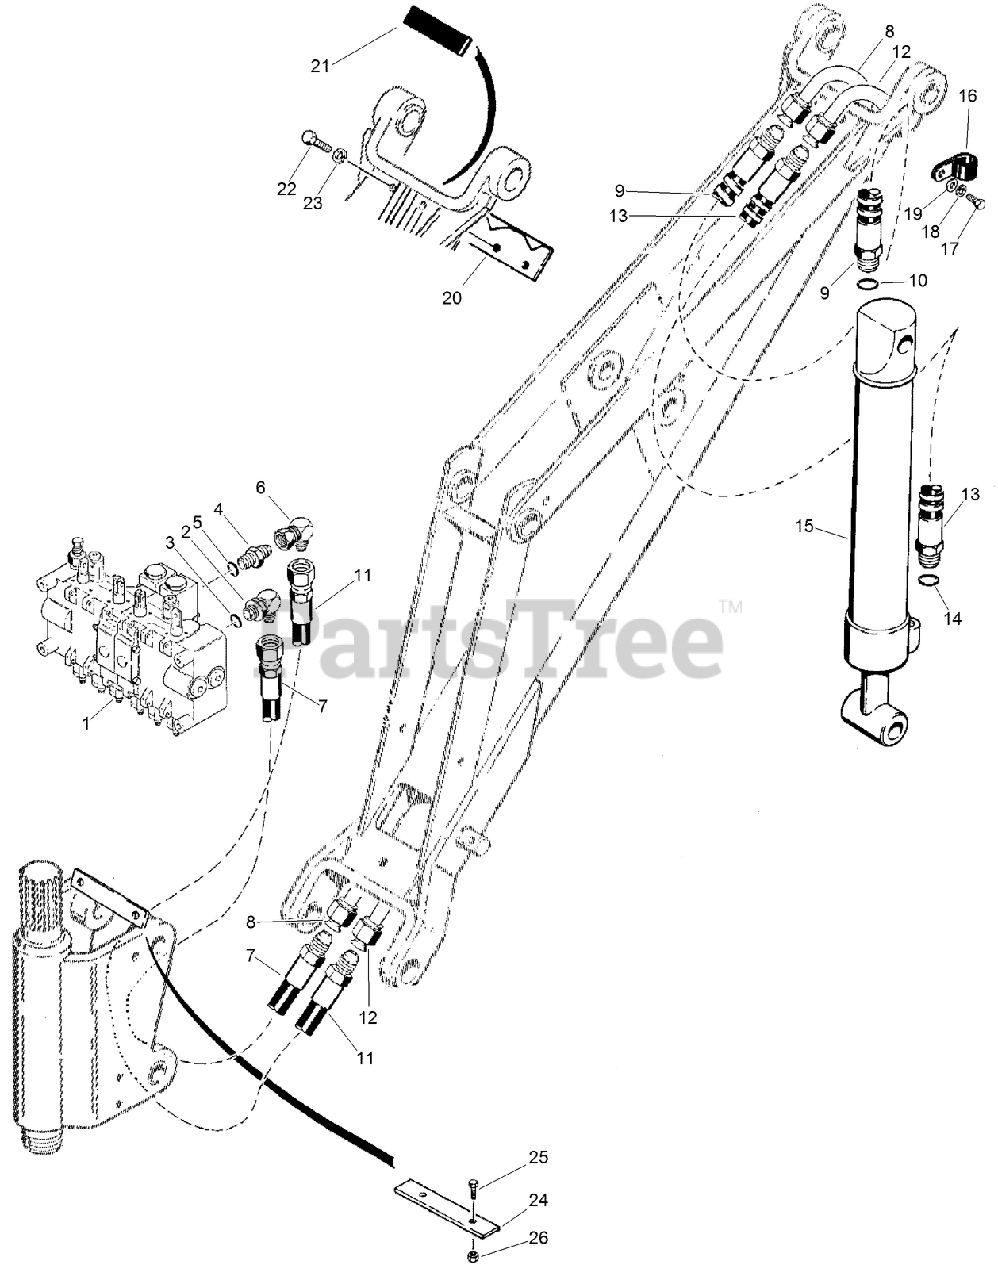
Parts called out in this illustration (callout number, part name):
1	VALVE-Backhoe, w/Special Low Leak Spools
2	ELBOW-90 Adj 37FL, 1/2 Tube
3	O-RING
4	CONNECTOR-Str Thd 1/2, 37FL-ORB 1/2
5	O-RING
6	ELBOW-90 Swivel 37FL 1/2 Tube
7	HOSE-1225 mm (48-1/4 inch) long, control valve to tube
8	TUBE-intermediate, to closed end of bucket cylinder
9	HOSE-1067 mm (42 inch) long, at closed end of bucket cylinder
10	O-RING
11	HOSE-1225 mm (48-1/4 inch) long, control valve to tube
12	TUBE-intermediate, to rod end of bucket cylinder
13	HOSE-1549 mm (61 inch) long, at rod end of bucket cylinder
14	O-RING
15	CYLINDER-Backhoe
16	CLAMP-Tube
18	WASHER-Spring Lock Reg 0.250 in ZND
19	WASHER-FLAT
20	CLAMP-tube, at boom
21	CUSHION-Anti-Wear
22	BOLT-Hex Hd 0.312 x 2.00 GR8 ZND
23	WASHER-Lock, 5/16 inch
24	BRACKET-Hose Mtg
25	BOLT-Hex Hd 0.250 x 1.50 GR8 ZND
26	NUT-Prev Trq 1/4 GRA CAD NONDIR
